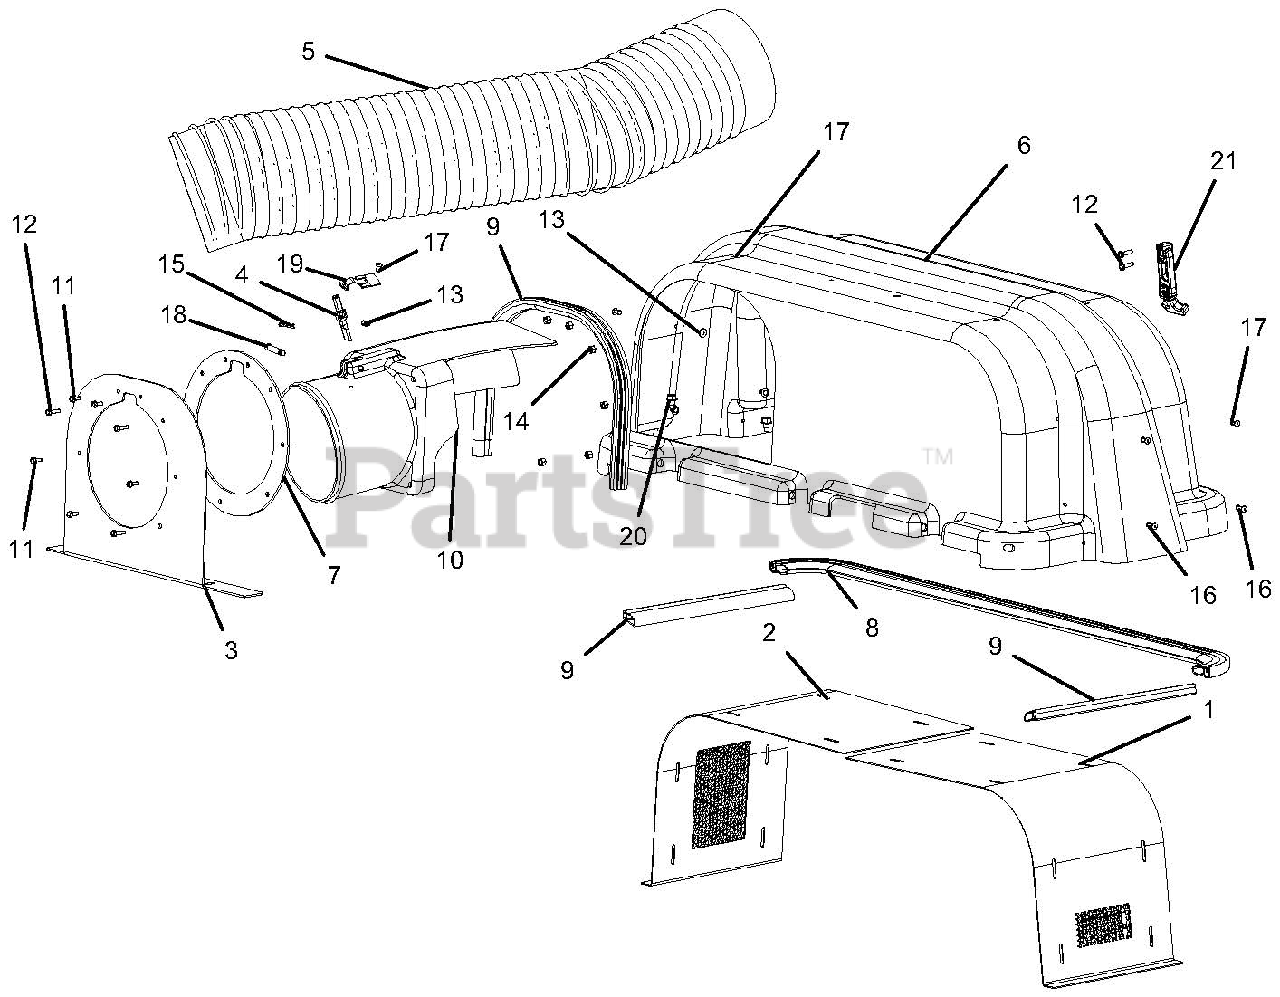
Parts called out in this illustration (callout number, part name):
1	WMT-BAGGER HOOD VENT, LH
2	WMT-BAGGER HOOD VENT, RH
3	WLDMT, TUBE SUPPORT
4	INDICATOR, FLOW
5	HOSE, FLEXIBLE-47"
6	COVER, 2-BUCKET BAGGER
7	SEAL, UPPER BOOT
8	SEAL, BULB - BAGGER HOOD
9	SEAL, BULK
10	BOOT, UPPER
11	@SCR-MCH 10-24X.50 HWH YWZC
12	@SCR-MCH 10-24X.75 HWH YWZC
13	@WSHR-FL-STL.219X.50X.049 YWZC
14	@NUT-LK-NYL 10-24 W/INSRT YWZC
15	PIN-HAIR, ENDRIES #25 YWZC
16	.187X.6835 DOME ST
17	RVT-POP.187X.527 DOME ST
18	PIN-CLEV .309 X 1.625 YWZC
19	THUMB LATCH
20	@SCR-TAP .31-18X.50 HWH TR YWZ
21	LATCH, RUBBER
